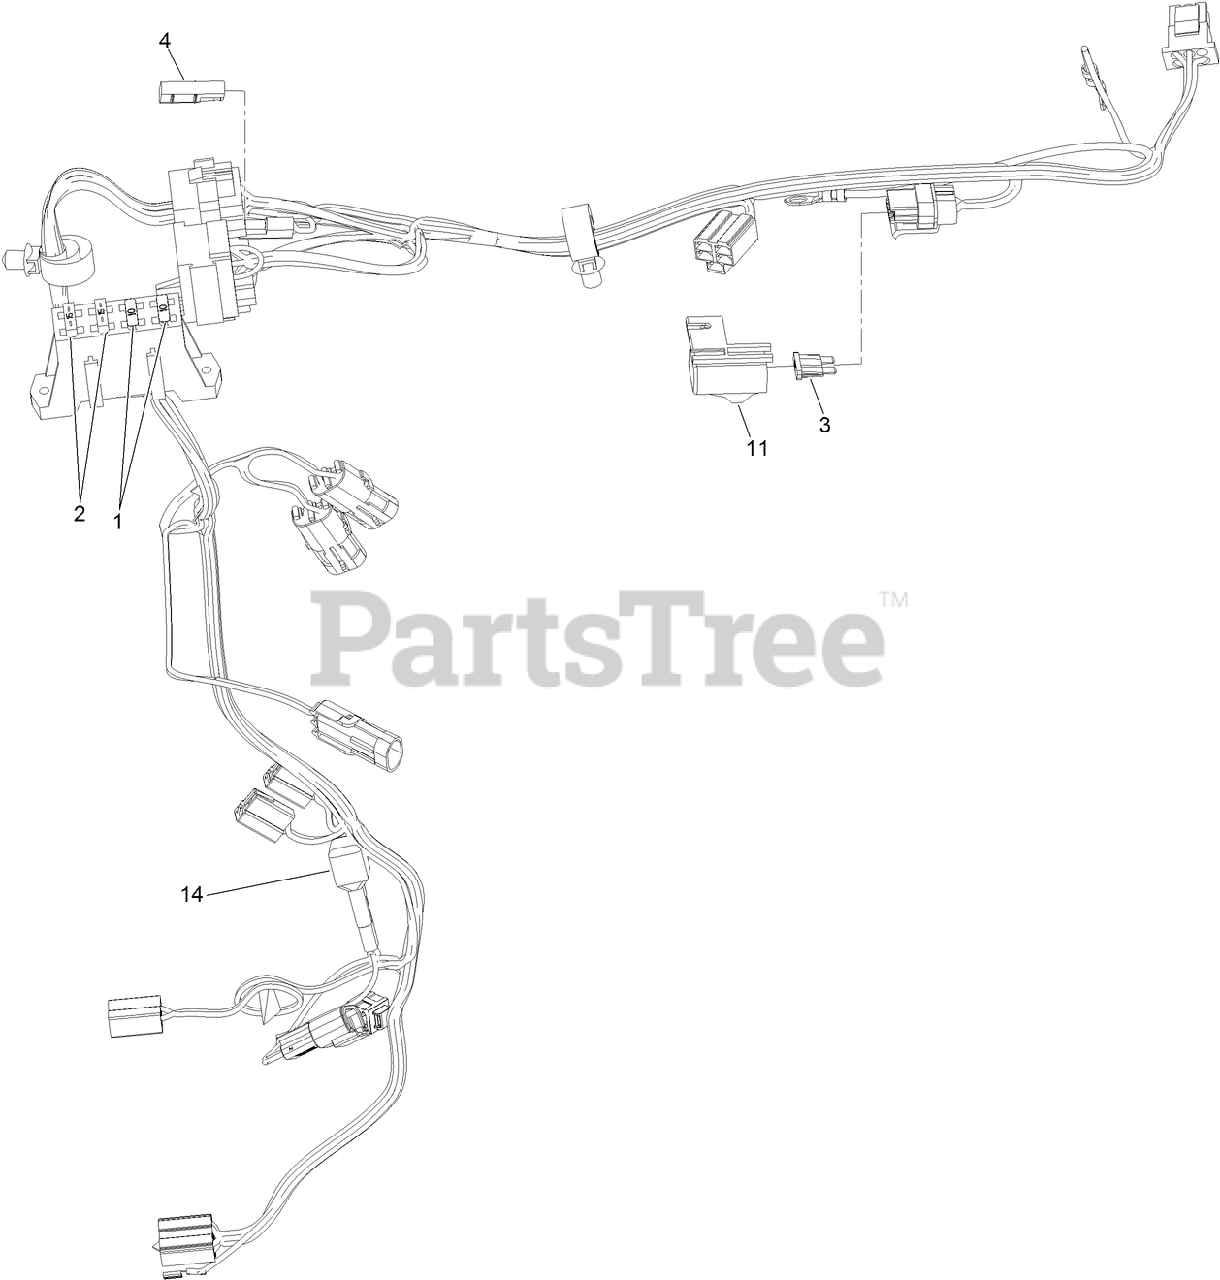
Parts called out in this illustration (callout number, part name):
1	FUSE-BLADE, 10 AMP
2	FUSE-BLADE, 15 AMP
3	FUSE-BLADE, 30 AMP
4	CAP-PLUG
11	COVER-FUSE, SINGLE
14	RESISTOR (1.6K OHM)
